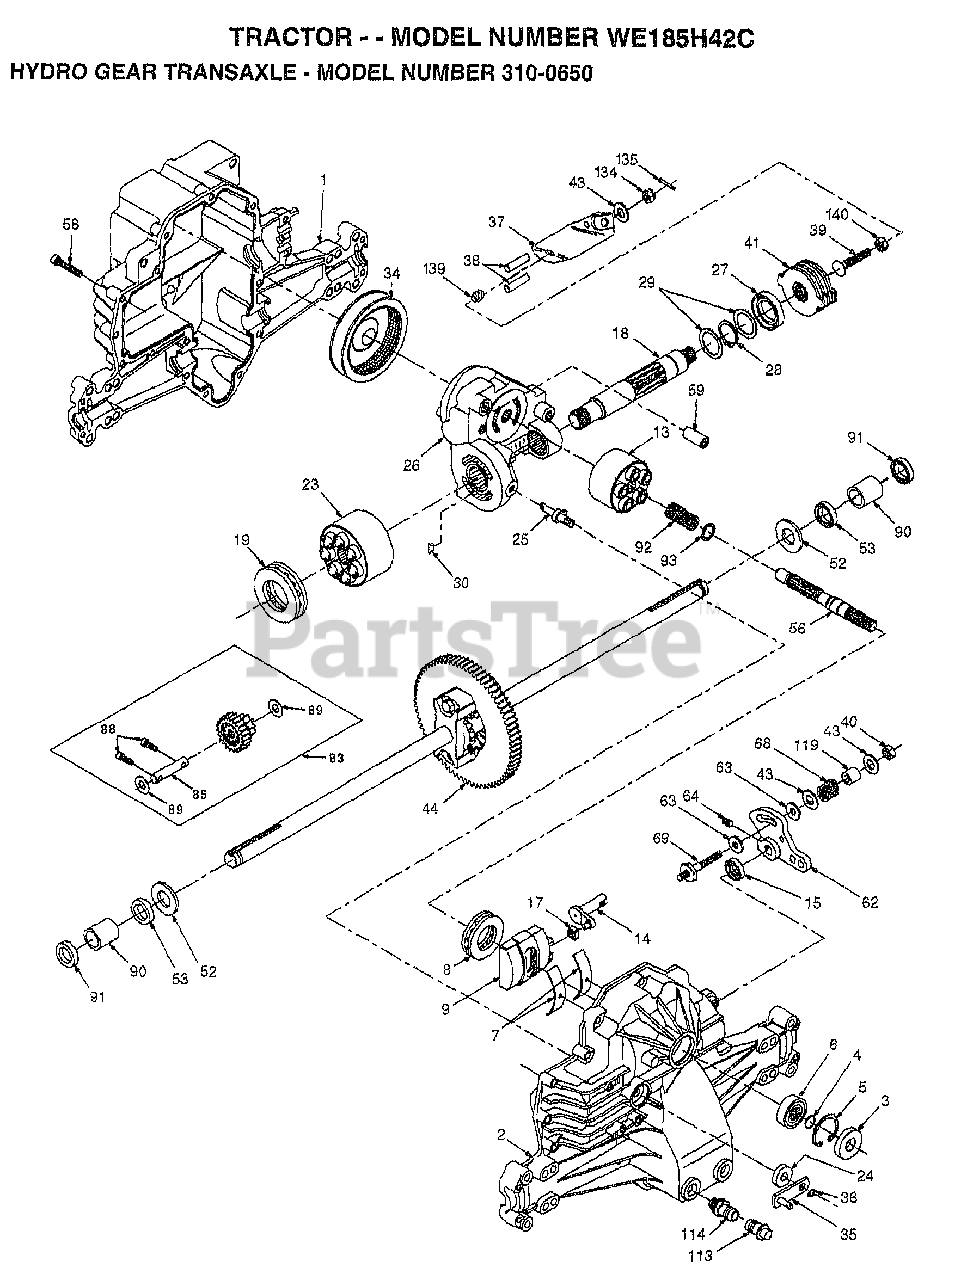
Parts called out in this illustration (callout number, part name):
1	HOUSING.L.50074RM
2	HOUSING.UP.70125
3	SEAL.9008000-0128
4	RING.RET.2003016.
5	RING.RET.2003052.
6	BEARING.(50552)42X68X16
7	CRADLE- 2003023.
8	BEARING.THU.50551
9	SWASHPLT.2003087.
13	BLOCK.CLYN.70079.
14	ARM.TRUN.2003005.
15	SEAL.9008000-0126
17	GUIDE.2000015.
18	SHAFT.MOTOR.50449
19	BEARING.THU.50552
23	BLOCK.CYLIN.70082
24	SEAL.LIP.45074
25	ACTUATOR.2003555
26	KIT.CEN.SEC.70250
27	SEAL.LIP.45075
28	RING RETAIN 50007
29	WASHER.44872
30	PLATE.BYP.2003554
34	ELEMENT.OIL.44964
35	ARM.BYPASS.50270
36	RING.RETAIN.44870
37	ARM.ACTUAT.23710
38	PIN.ACTUAT.44891
39	BOLT.50316
40	NUT.LOCK.HX.50317
41	KIT.BRAKE.70135
43	WASHER HYD 44130
44	DIFFRENTIAL.70226
52	WASHER.HYD.44875
53	SEAL.HYDRO.45076
56	SHAFT.INPUT.50005
58	BOLT.1/4-20.44876
59	PIN.HYDRO.50002
62	ARM.CONTROL.50254
63	PUCK.DAMPER.50281
64	SCREW.SET.50018.
68	SPRING.HYD.50277
69	STUD.5/16-24.DANA
83	JACKSHAFT/PINION GEAR.70132
85	PIN.SHAFT 50559
88	SCREW.CAP.50154.
89	WASHER.HYD.50132
90	BEARING.SLV.50118
91	SEAL.WIPER.50941
92	SPRING.2003014.
93	WASHER.2003017
113	CAP.VENT.70109
114	O-RING.ASM.70110
119	SPACER.HYD.50278
134	NUT.CAS.HYD.44142
135	PIN.COT.HYD.44101
139	SPRING.COMP.50431
140	NUT.HEX.50269
